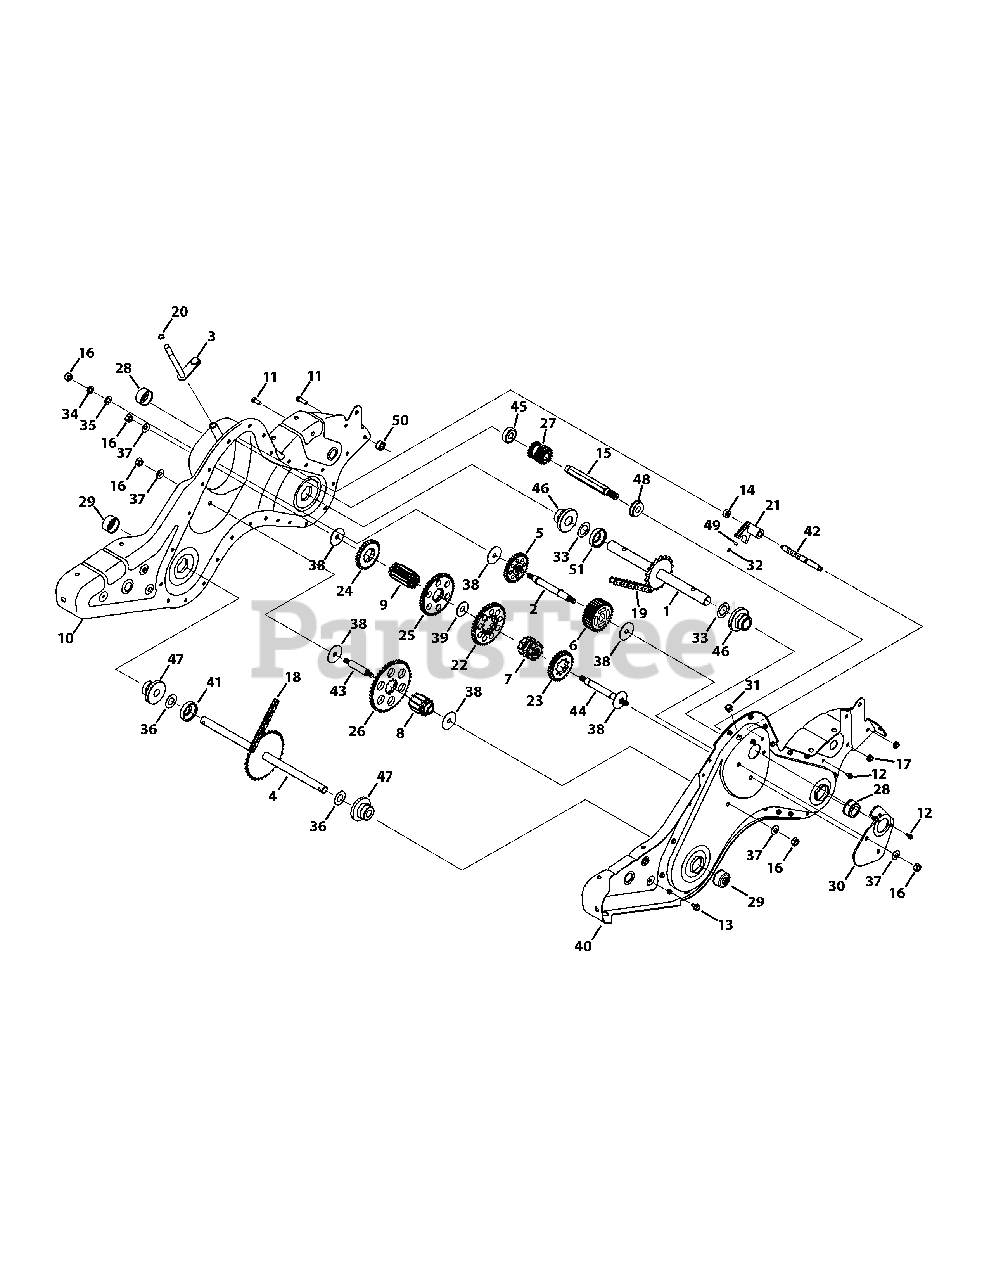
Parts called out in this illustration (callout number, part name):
1	Shaft Assembly, Tine, 18T
2	Shaft Assembly, Jack
3	Shaft Assembly, Shift Input
4	Shaft Assembly, Wheel, 33T
5	Gear Assembly, 30T Reverse Idler
6	Gear Assembly, 30T Tine Idler
7	Sprocket Assembly, 9T Tine Input
8	Sprocket Assembly, 10T Whl Input
9	Gear Assembly, 11T
10	RH Chain Case Housing Assembly
11	Hex Head Screw, 5/16-18 x 1.00
12	Screw, 1/4-20 x 0.625
13	Screw, :5/16-18 x 0.75
14	Spacer, .505 ID x .88 OD x .440
15	Input Shaft, .75
16	Nut, Hex, 7/16-20
17	Nut, Flangelock, 5/16-18
18	Endless Chain, #420 x 50 Links
19	Endless Chain, #50 x 54 Links
20	Snap Ring, .500
21	Clutch Collar
22	Gear Spur, 44T
23	Gear Spur, 30T
24	Gear Spur, 30T
25	Gear Spur, 44T
26	Gear Spur, 44T
27	Gear Spur, 16T
28	Shaft Seal, 1.0
29	Shaft Seal, .75
30	Positioner Gear Bracket
31	Tapered Cap Plug
32	Compression Spring, .230 OD
33	Washer, Flat, 1.03 x 1.62 x .03
34	Washer, Lock, 7/16
35	Washer, Flat,.474 x .879 x .064
36	Washer, Flat, .760 ID x 1.50 OD
37	Washer, Bell,.45 x 1.00 x .062
38	Washer, Thrust, .445 x 1.92 x .060
39	Washer, Flat,1.595 x .635 x .062
40	LH Chain Case Housing
41	Spacer, .75 x 2.0 x .50
42	Shaft Detent, .5 DIA
43	Shaft, Jack, .625 x 2.385
44	Shaft, Jack, .6250 x 5.0050
45	Ball Bearing, 17 x 40 x 12:6203
46	Flange Bearing, 1.0 x 2.5 x 1.38
47	Flange Bearing, .75 x 2.5 x 1.38
48	Ball Bearing, 17 x 40 x 12:6203
49	Ball, Detent, .250
50	Spacer, .315 x .750 x .375 LG
51	Spacer, 1.0 ID x 2.0 OD x.5 LG
